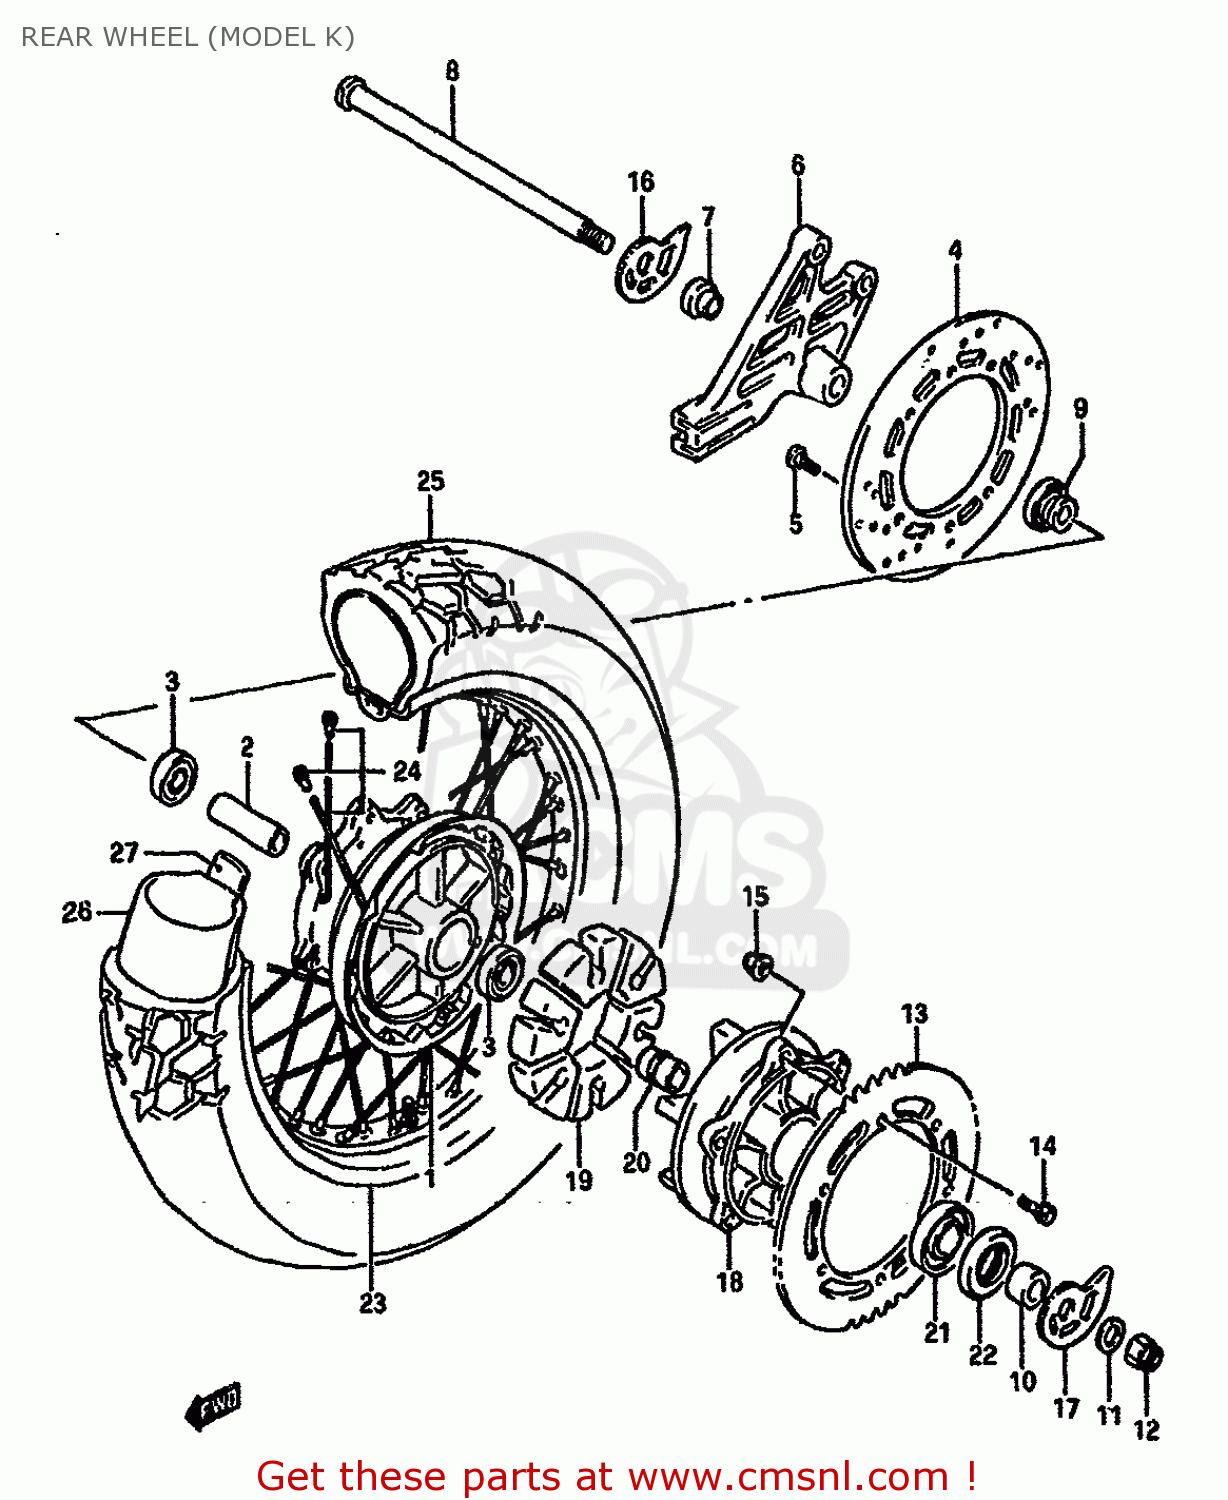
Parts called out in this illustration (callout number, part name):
1	HUB COMP,REAR WHEEL
2	SPACER(17.5X25X78)
3	BEARING
4	DISC,RR BRAKE
5	BOLT,BRAKE DISC
6	BRACKET,RR CALIPER
7	SPACER (17X21X10)
8	AXLE,RR
9	SPACER,RR AXLE,L
10	SPACER(17X33X22.4)
11	WASHER (17X30X3.2)
12	NUT
13	SPROCKET,REAR (NT:48)
14	BOLT(8X30.5)
15	NUT
16	ADJUSTER,CHAIN,RH
17	ADJUSTER,CHAIN,LH
18	DRUM,REAR SPROCKET
19	ABSORBER,RR HUB SHOCK
20	RETAINER,RR SPROCKET DRUM
21	BEARING(25X62X17)
22	SEAL,OIL(33X62X7)
23	RIM,REAR WHEEL (17XMT2)
24	SPOKE SET,RR
25	TIRE,REAR (130/80-17 65S)
26	TUBE ASSEMBLY,WHEEL,INNER
27	PROTECTOR,WHL INR TUBE
28	SEAL,OIL(33X62X7)
29	RIM,RR WHEEL(17XMT2.50)
30	SPOKE SET
31	TIRE
32	TUBE ASSEMBLY,WHEEL,INNER
33	PROTECTOR,INNER TUBE
